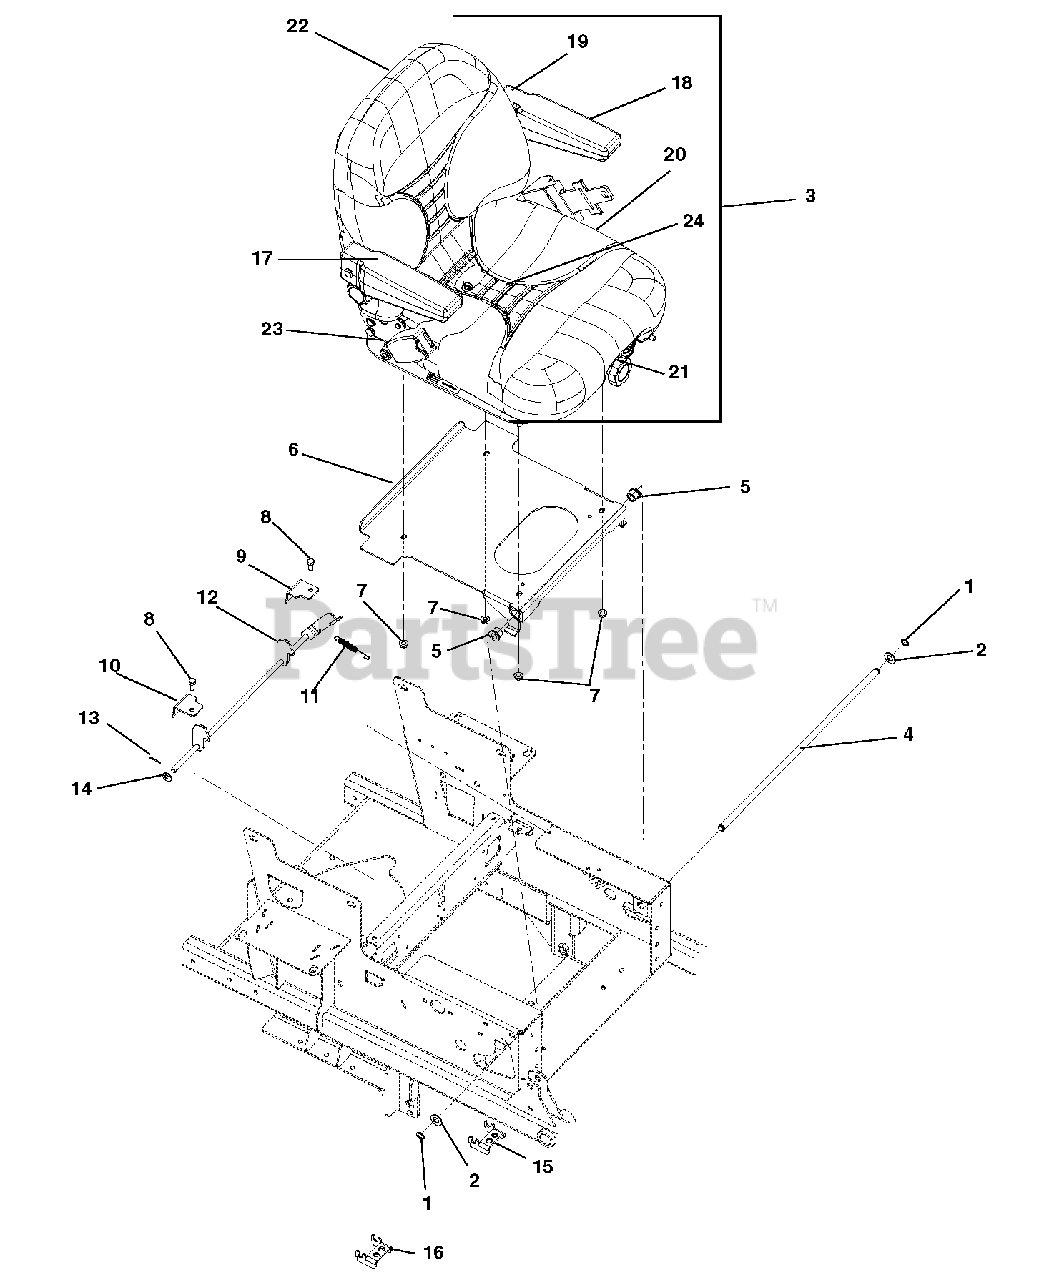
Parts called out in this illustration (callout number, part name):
1	Ring, Retaining-External .500 x .050
2	Washer, Flat Steel .531 x 1.00 x .063
3	Seat, Suspension -with Belt, Light Gray
4	Shaft, 100I Seat Pivot
5	Bushing, Flange .516 x .750 x .625 x .937
6	Seat Plate Weldment
7	Nut, Locking-Top-Flange .31-18
8	Bolt-Hex .31-18X.75 Grade 5
9	Pro-Turn 100 Left Hand Top Seat Latch Mount
10	Pro-Turn 100 Right Hand Top Seat Latch Mount
11	Spring, Tension .043 x .44 x 3.31
12	Pro-Turn 100 Seat Latch Weldment
13	Pin, Center .09 x .75 Extended Prong Square Cut
14	Washer, Flat-Steel .406 x .812 x .065
15	Pro-Turn 100 Right Hand Seat Latch Mount Weldment
16	Pro-Turn 100 Left Hand Seat Latch Mount Weldment
17	Kit, Right Hand Armrest Assembly
18	Kit, Left Hand Armrest Assembly
19	Kit, Back Cushion, Light Grey
20	Kit, Seat Cusion, Light Grey
21	Kit, Seat Knobs
22	Kit, Seat Back
23	Kit, Seat Slides
24	Kit, Seat Spring and Saddle
